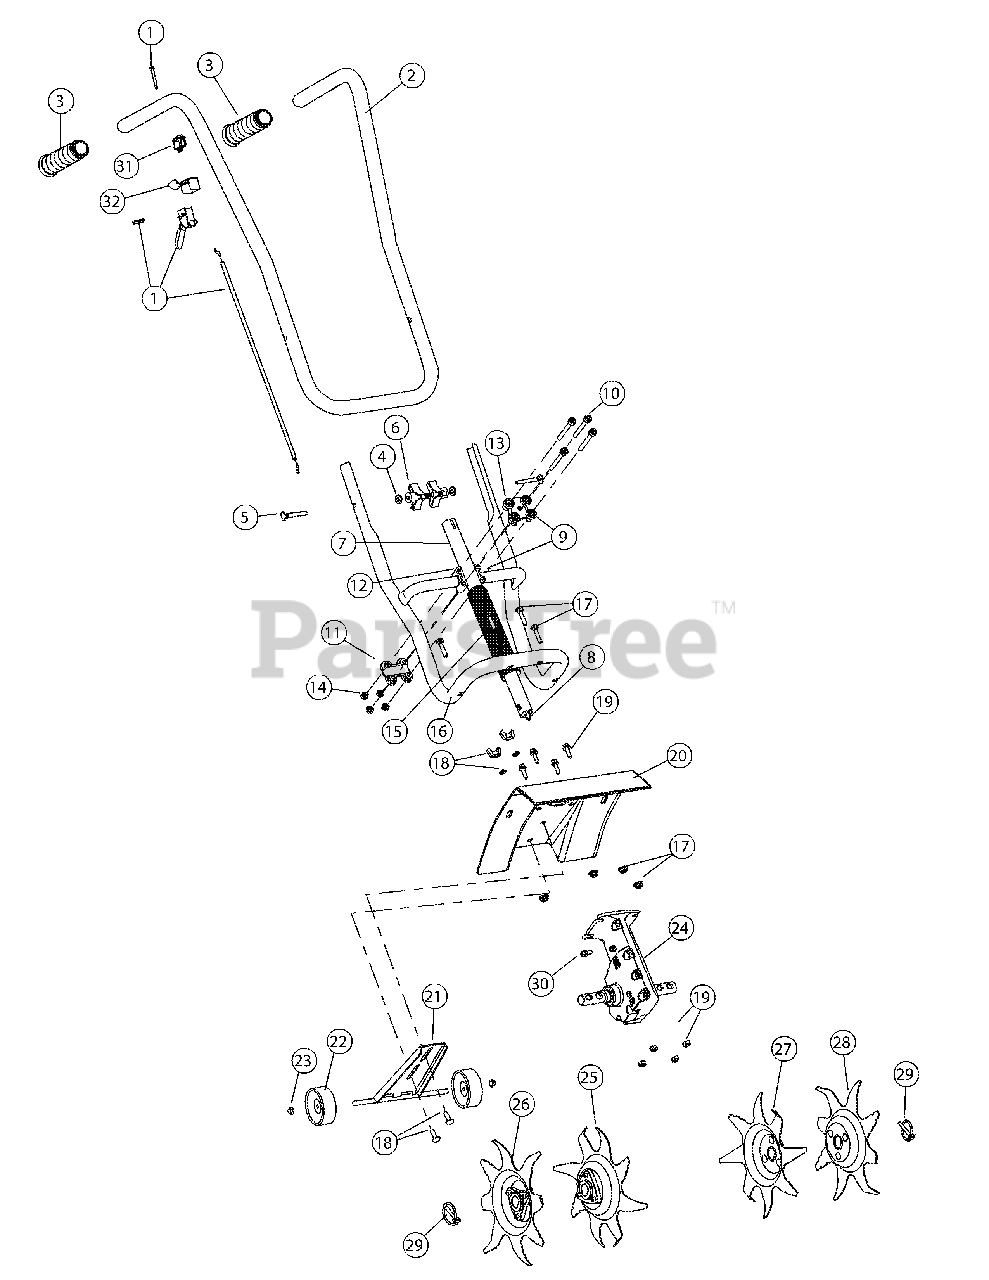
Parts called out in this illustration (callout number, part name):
1	Throttle Trigger and Cable Assembly
2	Handle Bar As sem bliy, Upper
4	Washer
6	Knob, 3 prong
7	Drive Shaft Housing Assembly
8	Flexible Drive Shaft
9	Handle Bracket Assembly
11	Upper Handle Clamp
12	Middle Handle Clamp
13	Lower Handle Clamp
16	Lower Handle Bar
17	Hardware, Handle Bar Mounting (lower)
18	Wheel Bracket Mounting Hard ware
19	Guard Mounting Hardware
21	Wheel Bracket Assembly
22	Wheel
23	Wheel Cap
24	Gearbox Assembly
25	Inner Tine (right side)
26	Outer Tine (right side)
27	Inner Tine (left side)
28	Outer Tine (left side)
29	Click Pin
30	Sleeve Retainer Bolt
32	Bracket
